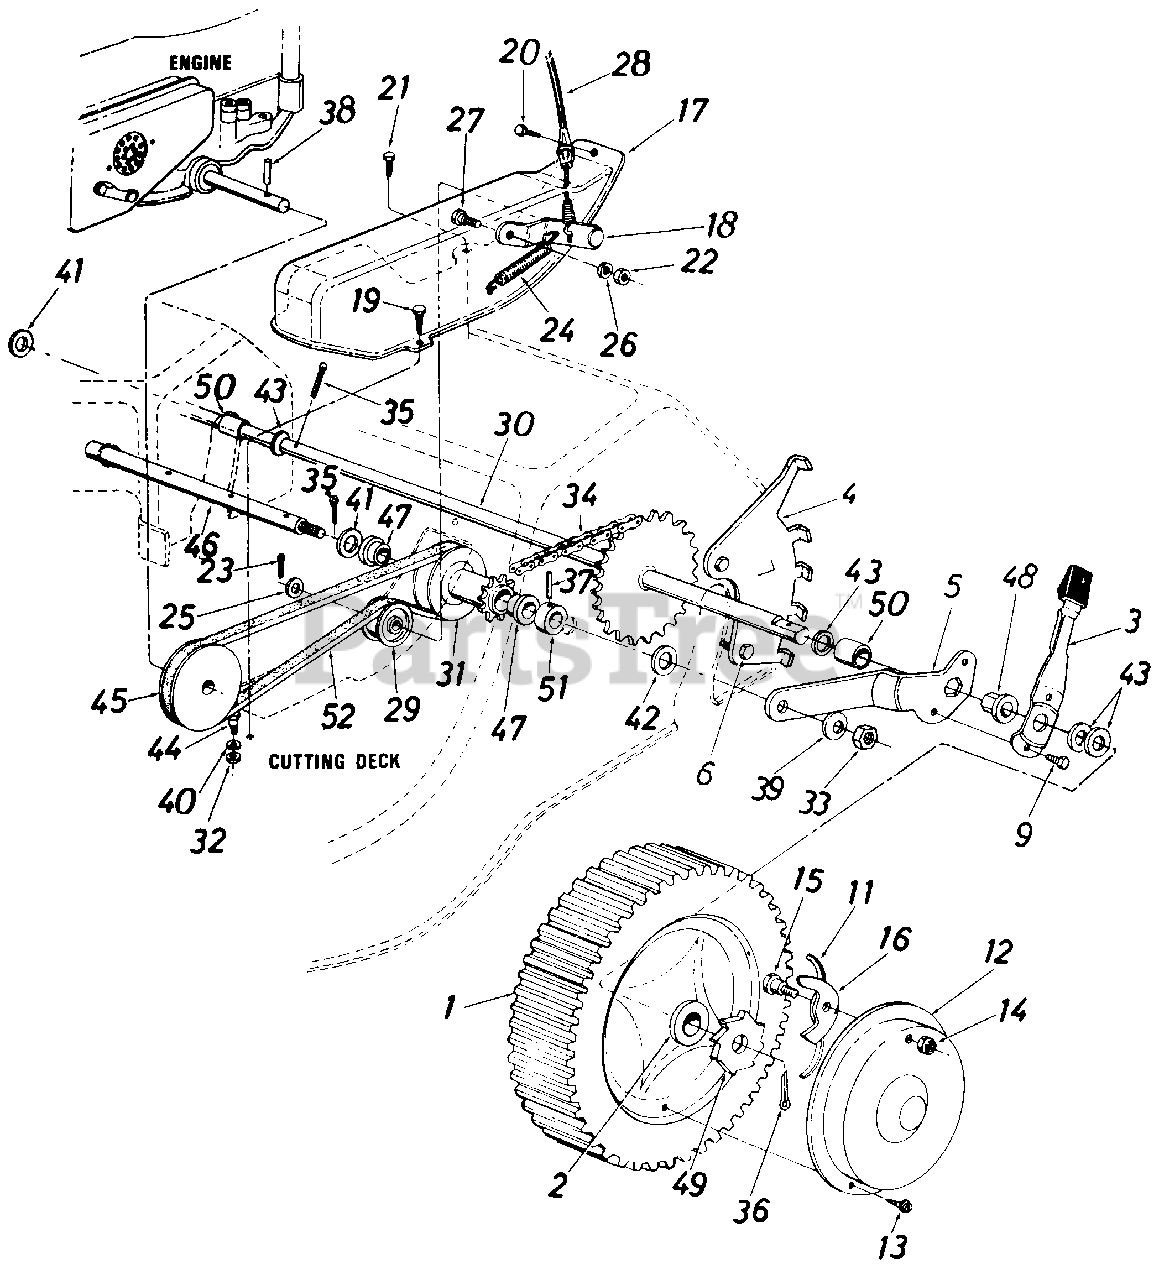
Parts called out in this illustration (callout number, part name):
1	Wheel Ass'y. Comp. 8.0 x 1.75
2	Flange Brg. 1/2" I.D.
3	Spring Lever w/Knob
4	Index Plate Ass'y. L.H.
5	Pivot Brk't. L.H.
6	Hex Wash. Hd. Tap Scr. 1/4 x .62
9	Hex B-Tap Scr. 1/4 x .38"
11	Nylon Spring
12	Hub Cap
13	Pan Hd. Tap Scr. #12 x .50"
14	Hex Ins. L-Nut 1/4-20 Thd.
15	Shld. Bolt .342" Dia. x .268
16	PawI
17	Belt Cover
18	Idler Bracket Ass'y.
19	Hex Wash. Hd. Self-Tap Scr. 1/4-20 x .50" Lg.
20	Hex Drilling Scr. #10 x .50"
21	Hex TT-Tap Scr. 1/4-20 x .75"
22	Hex Nut 1/4-20 Thd.
23	Cotter Pin 118" Dia. x 1.00"
24	Extension Spring .33" O.D. x 1.12" Lg.
25	Fl-Wash. .531" I.D. x .930" O.D.
26	L-Wash. 1/4" I.D.
27	Shld. Bolt.375" Dia. x .181
28	Clutch Cable 50"
29	Flat Idler Plastic
30	Rear Shaft Ass'y.
31	Pulley w /9Tooth Sprocket Ass'y.
32	Hex Nut 5/16-18 Thd.
33	Hex Jam Nut 3/8-16 Thd.
34	#48 Chain 1/2" Pitch x 31 Links
35	Cotter Pin 3/32" Dia. x 1.00"
36	Cotter Pin 1/8".Dia. x 1.00"
37	Spring Pin Spir. 3116" Dia. x 1.00" Lg.
38	Spring Pin Spir. 3/16" Dia. x 1.50" Lg.
39	Bell-Wash. .400" I.D. x .88" O.D.
40	L-Wash. 5/16" I.D.
41	Fl-Wash. .531" I.D. x .930" O.D.
42	Bell-Wash. .400" I.D. x 1.13" O.D.
43	Fl-Wash. .510" I.D. x 1.0" O.D
44	Shld. Bolt .437" Dia. x .470"
45	Engine Pulley
46	Pulley Shaft
47	Flange Brg. .506" I.D. Plastic
48	Hex Flange Brg. .506" I.D. Plastic
49	Ratchet
50	Spacer.765" I.D. x .89" O.D. x .960" Lg.
51	Spacer.505" I.D. x .88" O.D. x .44" Lg.
52	"V"-Belt 1/2" x 31" Lg.
